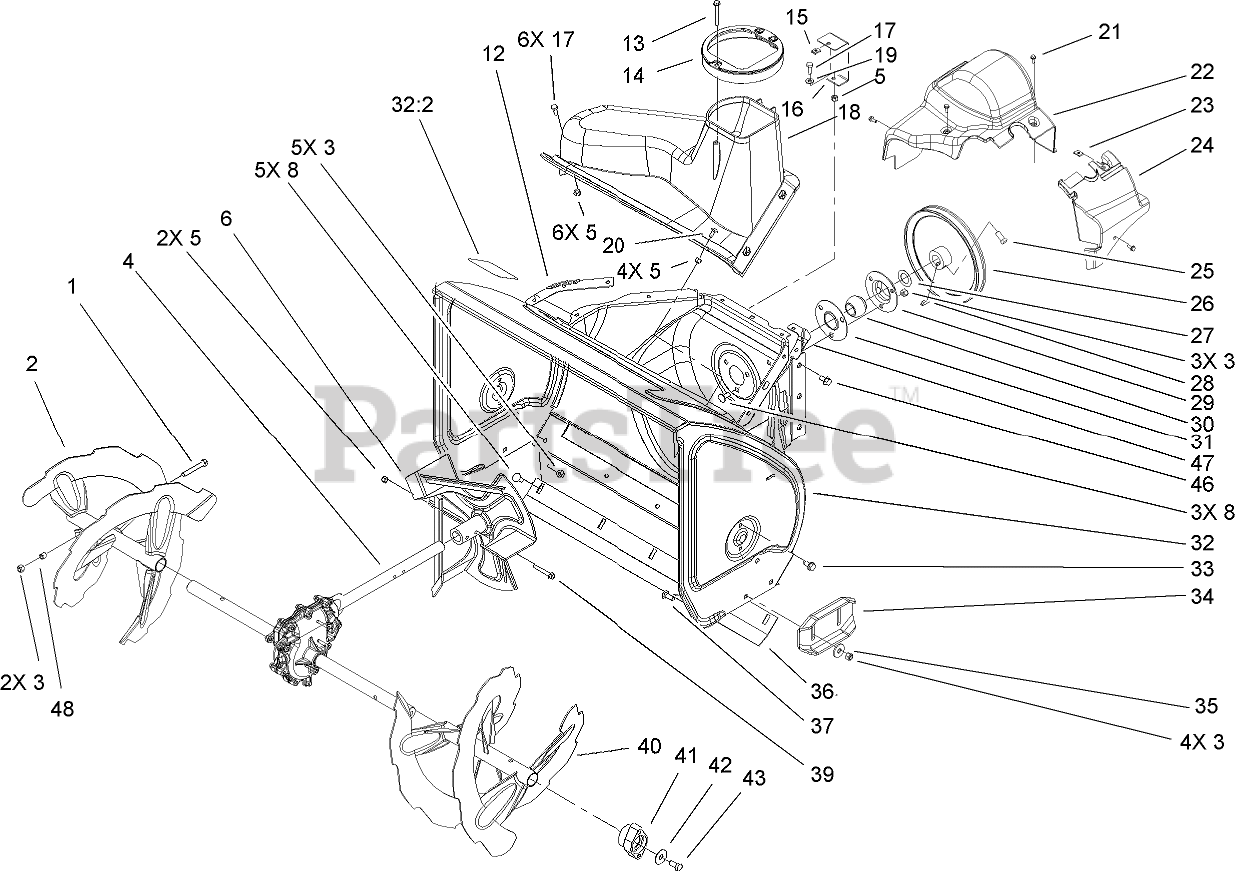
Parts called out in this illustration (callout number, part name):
1	SCREW-HH
2	RH AUGER ASM
3	NUT-LOCK, NI
4	26 INCH AUGER GEARCASE ASM
5	NUT-LOCK, NI
6	IMPELLER ASM
8	SCREW-CARR
12	SEAL-FLANGE, COVER
13	SCREW-PLASTITE
14	GUIDE-CHUTE
15	NUT-SPEED, U-TYPE
16	BRACKET-COVER, CLIP NUT
17	SCREW-HH
19	WASHER-FLAT
20	BOLT-CARR
21	SCREW-HWH
22	COVER-BELT
23	NUT-SPEED
24	COVER-EXTENSION, BELT
25	SCREW-SET, SQH
26	PULLEY-IMPELLER
27	WASHER-THRUST
28	KEY-WOODRUFF
29	FLANGE-CUP, BEARING
30	BEARING-BALL
31	FLANGE-CUP, BEARING
32	HOUSING-AUGER, 26 INCH
32:2	DECAL-WARNING, AUGER
33	SCREW-HWHTF
35	WASHER
36	SCRAPER-FIXED
37	SCREW-CARR
39	SCREW-HHF
40	LH AUGER ASM
41	BEARING-AUGER
42	WASHER
43	SCREW-HH
46	SCREW-HWHTF
48	SPACER
